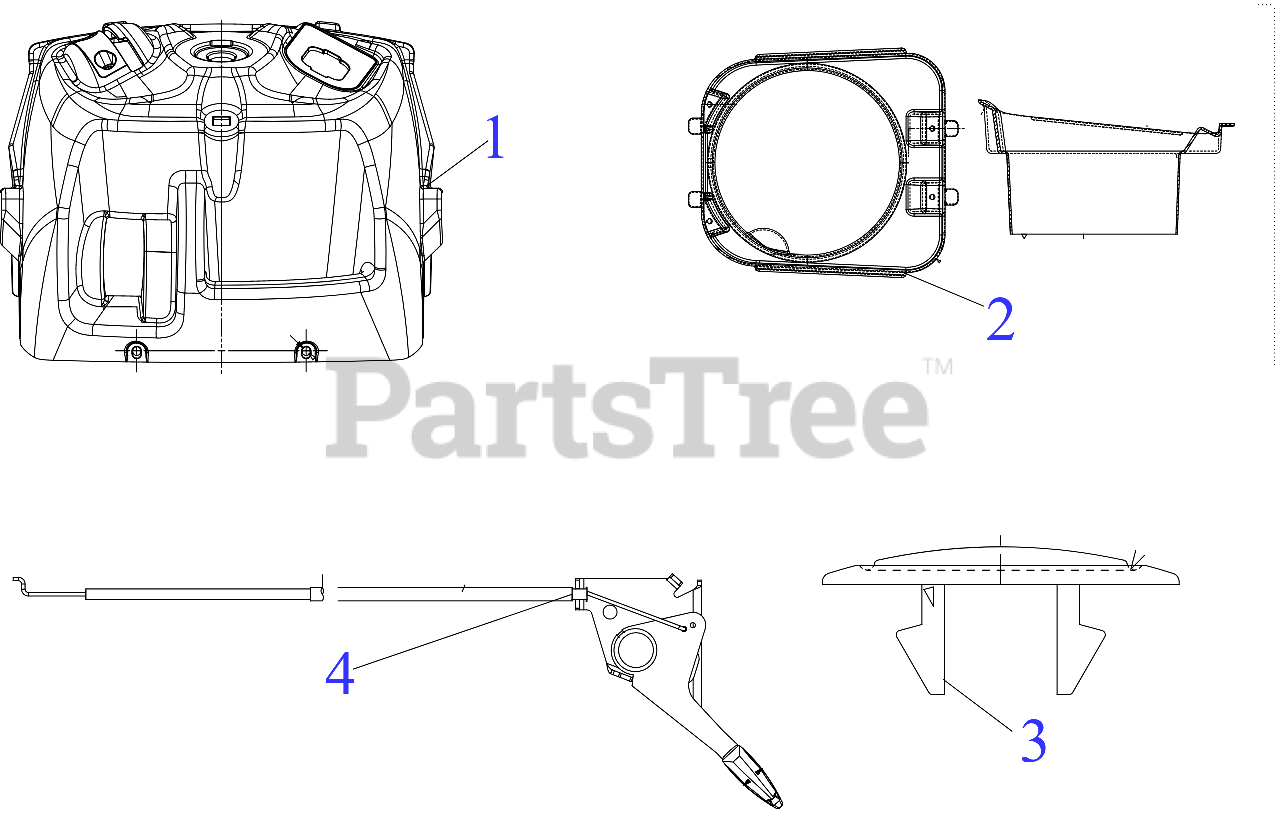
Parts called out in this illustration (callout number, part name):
1	UPPER DASH
2	HOOD PLENUM
3	CHOKE PLUG
4	THROTTLE CABLE 31" x 1.1
